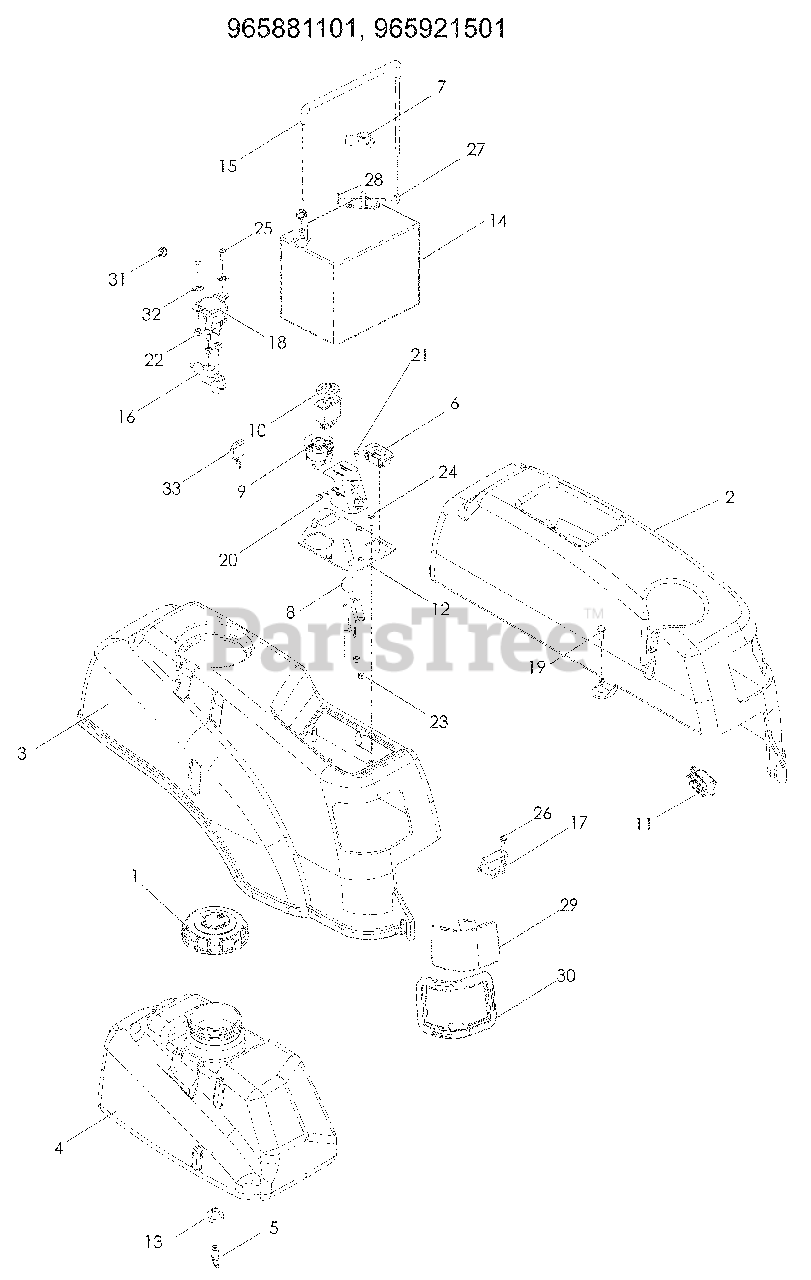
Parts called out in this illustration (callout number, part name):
2	FENDER, LT
3	FENDER, RT
4	TANK, FUEL
5	ELBOW, TANK
6	HOUR METER
7	COVER, TERMINAL
8	CABLE, THROTTLE
9	SWITCH, IGNITION
10	SWITCH, CLUTCH
11	SWITCH, BRAKE
12	PLATE, CONSOLE
13	GROMMET, RUBBER
14	BATTERY
15	TIE DOWN, BATTERY
16	COVER, TERMINAL
17	SWITCH, N.C.
19	BOLT ¼-20 x ½ HWST
20	DECAL, CONSOLE
21	SCREW 10-24 x ½ SLT HD
22	NUT ¼-20 HEX NYLOC
23	NUT 10-24 HEX NYLOC
24	SCREW 10-12 x ¾ WSHR HD
25	SCREW ¼-20 x 5/8 BTN SKT
26	SCREW 10-24 x 5/8 WSH HD
27	RHSNB 5/16-18 x ¾
28	NUT 5/16-18 FLANGE NYLOC
29	LENS, LT
30	LENS RIM, LT
31	NUT ¼-20 HEX NYLOC THIN
32	WASHER ¼ ITLW
33	KEY, IGNITION
